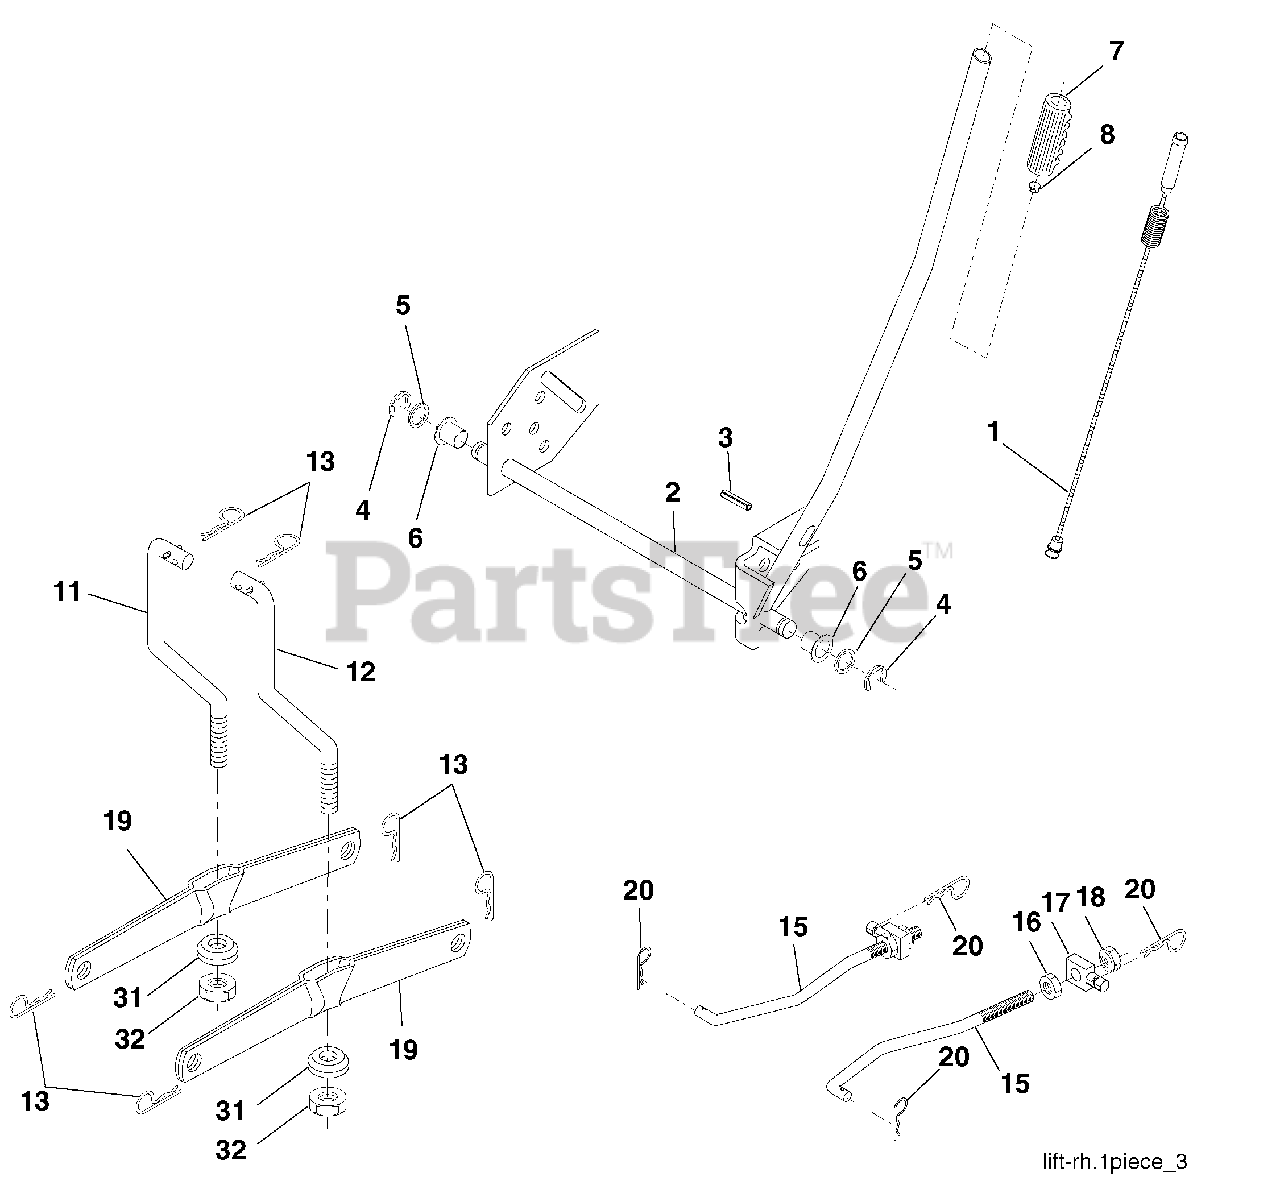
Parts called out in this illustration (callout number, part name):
1	Wire Asm Inner/Sprg w/Plunger
2	Shaft Asm Lift
3	Pin Groove
4	E Ring #5133-62
5	Washer 21/32 x 1 x 21 Ga.
6	Bearing Nylon
7	Grip Handle
8	Button Plunger
11	Link Lift Lh
12	Link Lift Rh
13	Retainer Spring
15	Link Front
16	Nut Jam Hex 1/2-13 unc
17	Trunnion Blk Zinc
18	Nut Lock w/Wsh 1/2-13 unc
19	Arm Suspension Rear
20	Pin Cotter 7/16 Bowtie Lock
31	Bearing Pvt Lift
32	Nut Crownlock 3/8-24
